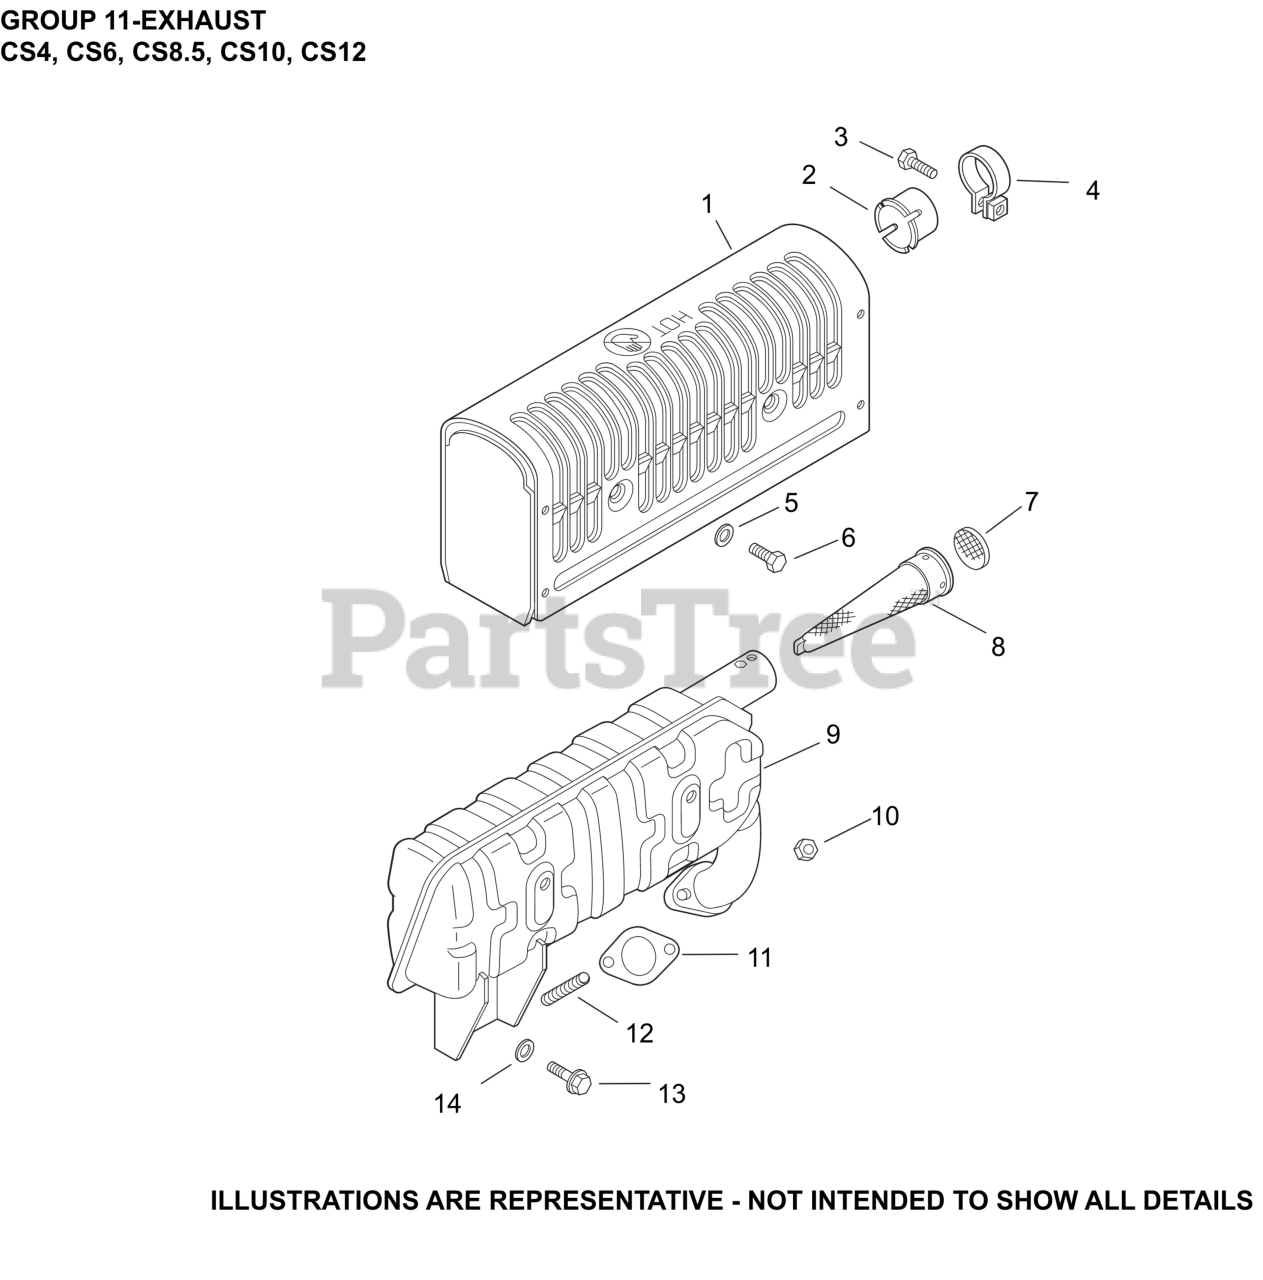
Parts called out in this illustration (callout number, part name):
NI	GASKET, EXHAUST
NI	SCREW, SELF-TAP
NI	SCREW, HEX FLANGE
NI	NUT, EXHAUST-(#DSC)
NI	SPARK ARRESTER
NI	MUFFLER GUARD KIT (LF)
